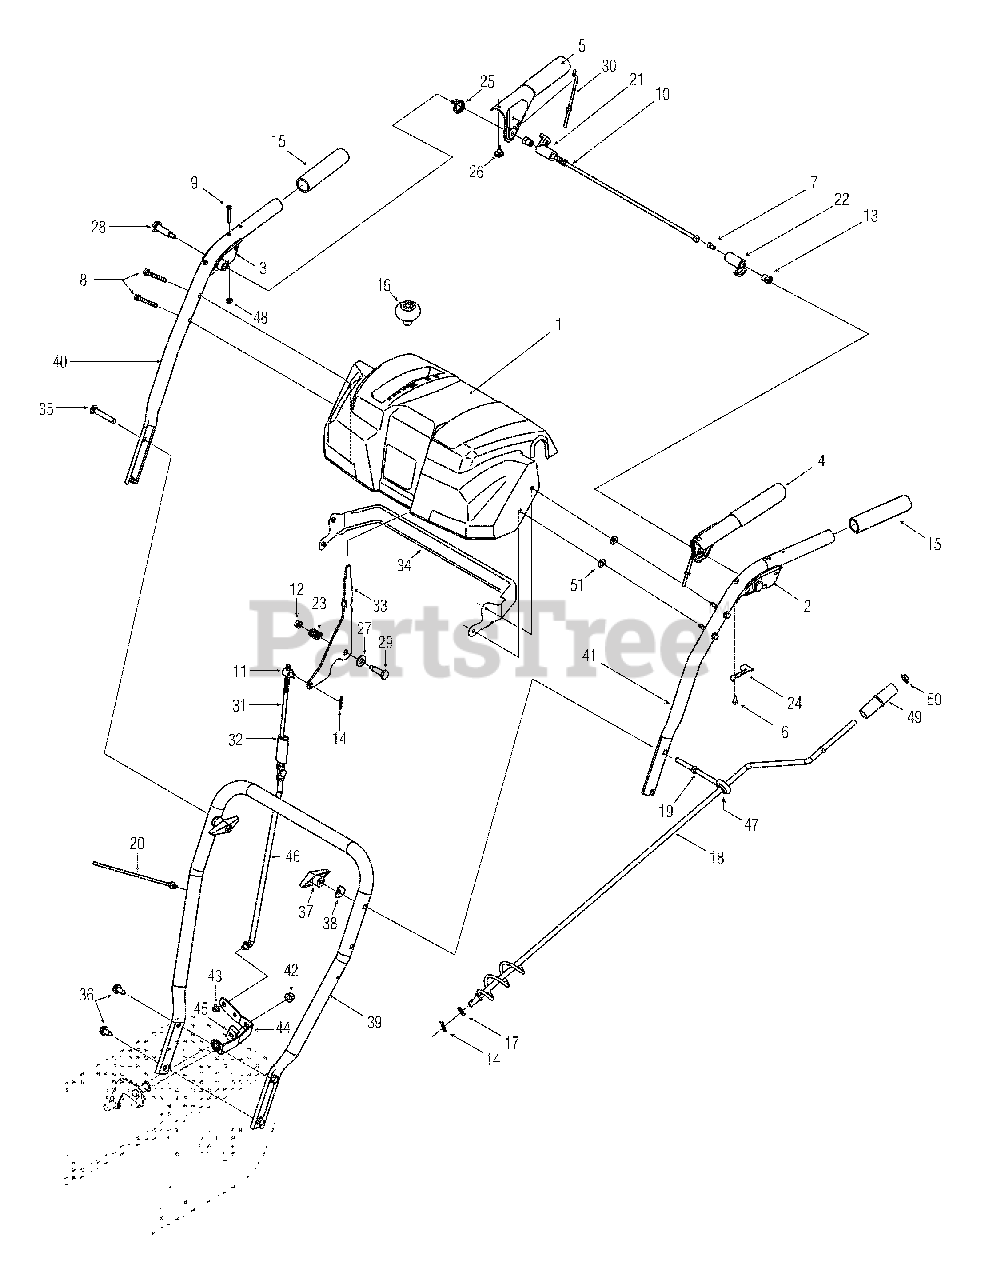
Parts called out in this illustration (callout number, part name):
1	Panel Assembly, Handle, N-Style
2	Handle Assembly, Clutch Lock, LH
3	Handle Assembly, Clutch Lock, RH
4	Handle Assembly, Engagement, LH
5	Handle Assembly, Engagement, RH
6	Screw, #8-16 x .50
7	Screw, 1/4-20 x .375
8	Screw, Self-tapping, 1/4-20 x 1.750
9	Screw, Machine, #10-24 x 1.375
10	Rod, Pivot
11	Ferrule, 5/16-18 x .312
12	Nut, Flange Lock, Nylon, 1/4-20
13	Nut, Shoulder, Hex, 1/4-20,
14	Pin, Cotter, .072 Dia. x 1.13
15	Grip, 1.0 ID x 5.0
16	Knob, Shift
17	Washer, Flat, .375 x .738 x .063
18	Crank Assembly, Chute
19	Eye Bolt, Chute Crank
20	Tie, Cable, 19 x 8.39", Tree Mount
21	Plate, Lock
22	Cam, Clutch Lock
23	Spring, Compression, .39 x .60 x .88
24	Spring, Clutch, Lock
25	Spring, Torsion, 0.8156 ID x .3038
26	Bumper, Rubber, .62 OD x .22
27	Washer, Flat, .385 x .870 x .092
28	Screw, Shoulder, .437 x 1.345, 1/4-20
29	Screw, Shoulder, .374 Dia. x 1.05
30	Z-Fitting, Cable
31	Shift Rod, Upper, .312 x 8.98
32	Connector Sleeve, Shift Rod
36	Screw, 5/16-12, 0.750
37	Wing Knob, 5/16-18
38	Washer, Saddle, 320 x .93 x .060
42	Nut, Flange Lock, Nylon, 5/16-18
43	Nut, Speed, .3125 Dia.
44	Spring Lever, Shift
45	Bracket, Shift Spacer
46	Shift Rod, Lower
47	Grommet, .44 ID x .94 OD x .50
48	Nut, Hex Lock, Nylon, #10-24, Gr2
49	Crank Knob, 1.0 Diameter x 3.2, Black
50	Cap, Push, 3/8 Rod
51	Washer, Flat, .25 x .630 x .051
